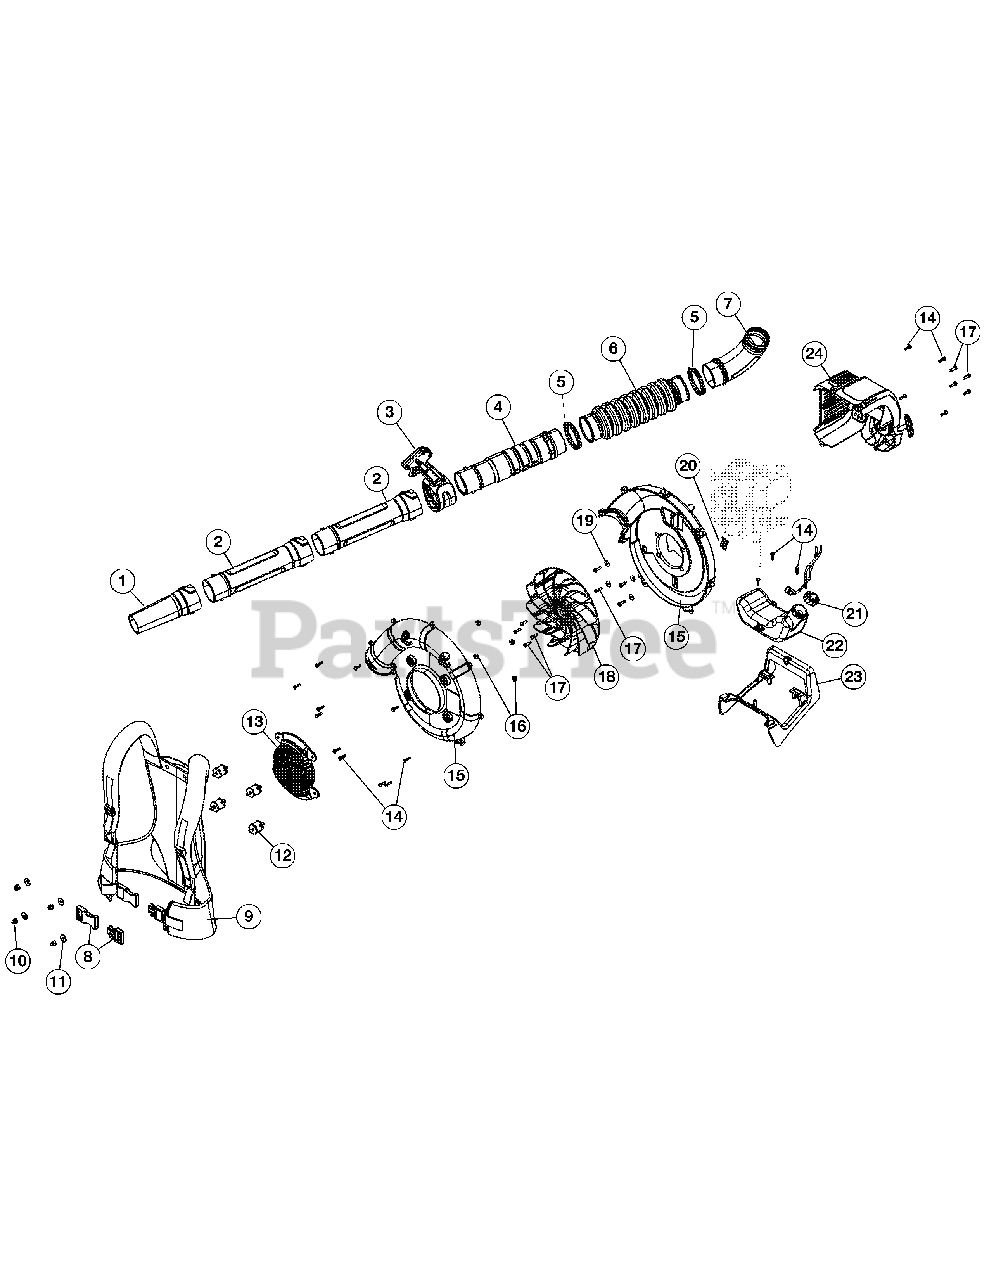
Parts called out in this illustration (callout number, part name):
1	Nozzle
2	Lower Blower Tube
3	Throttle Grip Assembly
4	Upper Blower Tube
5	Clamp
7	Elbow Tube
8	Harness Clip
9	Harness Only
9	Hip Belt for Harness
10	Nut
11	Spacer
12	Insulator Mount
13	Intake Cover
14	Screw
15	Impeller Housing Assembly
16	Nut
17	Screw
18	Impeller (includes 17)
20	Throttle Retaining Clip
22	Fuel Tank Assembly (includes 21)
24	Engine Cover Assembly
